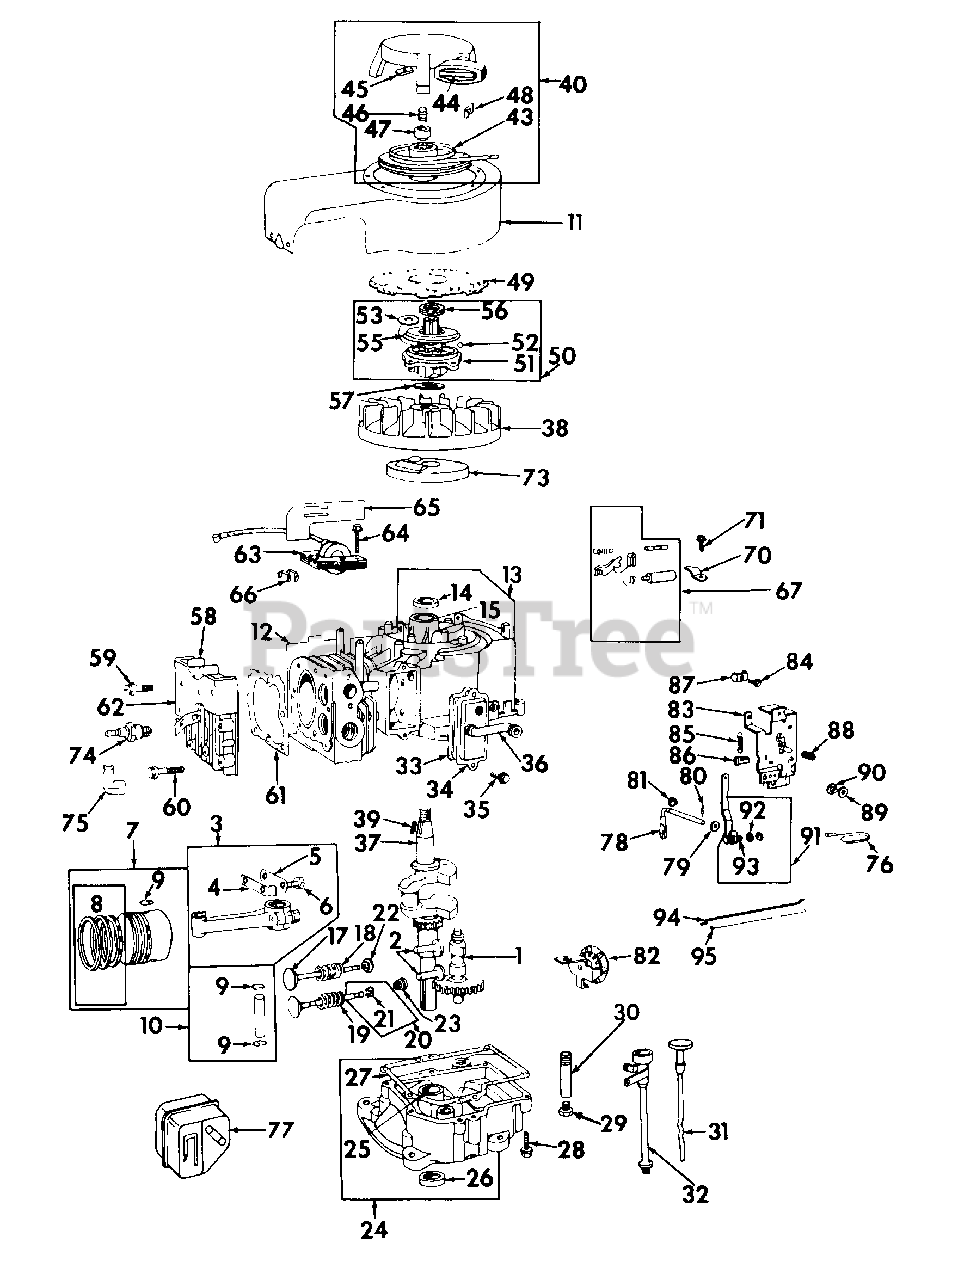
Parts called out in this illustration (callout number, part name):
2	TAPPET, VALVE
3	ROD ASSY, CONNECTING STD
4	DIPPER, CONNECTING ROD
5	LOCK, SCREW HEAD
6	SCREW, CONNECTING ROD
7	PISTON ASSY, STD
8	RING SET, PISTON CHROME- STD
9	LOCK, PISTON PIN
10	PIN, PISTON - STD
10	PIN, PISTON .005 U/S
11	HOUSING, BLOWER
12	SHIELD, CYLINDER
13	CYLINDER ASSY, ENGINE
15	BUSHING & SEAL
17	VALVE, INTAKE
18	SPRING, INTAKE VALVE
19	SPRING, EXHAUST VALVE
20	VALVE, EXHAUST
21	RETAINER, ROTO-COIL
22	RETAINER, INTAKE VALVE
23	ROTO-COIL, EXHAUST VALVE
24	SUMP ASSY, OIL
25	BUSHING & OIL SEAL
26	SEAL, OIL
27	GASKET, SUMP - STD
28	SCREW, SUMP MTG
29	PLUG, 1/4-18 AUTOMOTIVE HEX-HD PIPE
30	PIPE, OIL DRAIN
31	GAUGE, OIL LEVEL
32	TUBE, OIL LEVEL GAUGE
33	GASKET, BREATHER
34	BREATHER, VALVE CHAMBER
35	SCREW, BREATHER MTG
36	TUBE, BREATHER
38	FLYWHEEL -RECOIL START-
39	KEY, FLYWHEEL
40	STARTER ASSY, REWIND
43	SPRING, REWIND STARTER
44	PACKAGE, REWIND STARTER HANDLE & INSERT
45	BUMPER, REWIND PULLEY
46	SPRING, RATCHET SPRING
47	ADAPTER, RATCHET SPRING
48	SPRING, ANCHOR INSERT
49	SCREEN, REWIND STARTER
50	CLUTCH ASSY, REWIND STARTER
51	HOUSING, REWIND STARTER CLUTCH
52	BALL, 5/16 CR-STL- 25 GRADE
53	WASHER, THRUST
55	RETAINER, WASHER
56	SEAL, RATCHET
57	WASHER, SPRING
58	HEAD, CYLINDER
59	SCREW, CYLINDER HEAD-SHORT
60	SCREW, CYLINDER HEAD-LONG
61	GASKET, CYLINDER HEAD
62	COVER CYL HEAD
63	ARMATURE ASSY, MAGNETO
64	SCREW, ARMATURE MOUNTING
67	KIT, BREAKER POINT AND CONDENSER
70	CLAMP, CONDENSER
71	SCREW, CONDENSER CLAMP
73	COVER, BREAKER POINT
74	PLUG, SPARK -CHAMPION-
75	ELBOW, SPARK PLUG INSULATOR
76	WIRE, GROUND
77	MUFFLER, EXHAUST
78	CRANK, GOVERNOR
79	WASHER, GOVERNOR CRANK
80	COTTER, GOVERNOR CRANK
81	RETAINER, GOVERNOR CRANK
82	GEAR, GOVERNOR
83	PLATE, GOVERNOR
84	SCREW W/LOCKWASHER, HEX-HD
85	SPRING, GOVERNOR
86	SWITCH, STOP
87	CLAMP, CASTING
88	SPRING, THROTTLE ADJ
89	WASHER, INSULATING
90	COLLAR, INSULATING
91	LEVER ASSY, GOVERNOR
94	LINK, GOVERNOR
95	SPRING, GOVERNOR LINK
